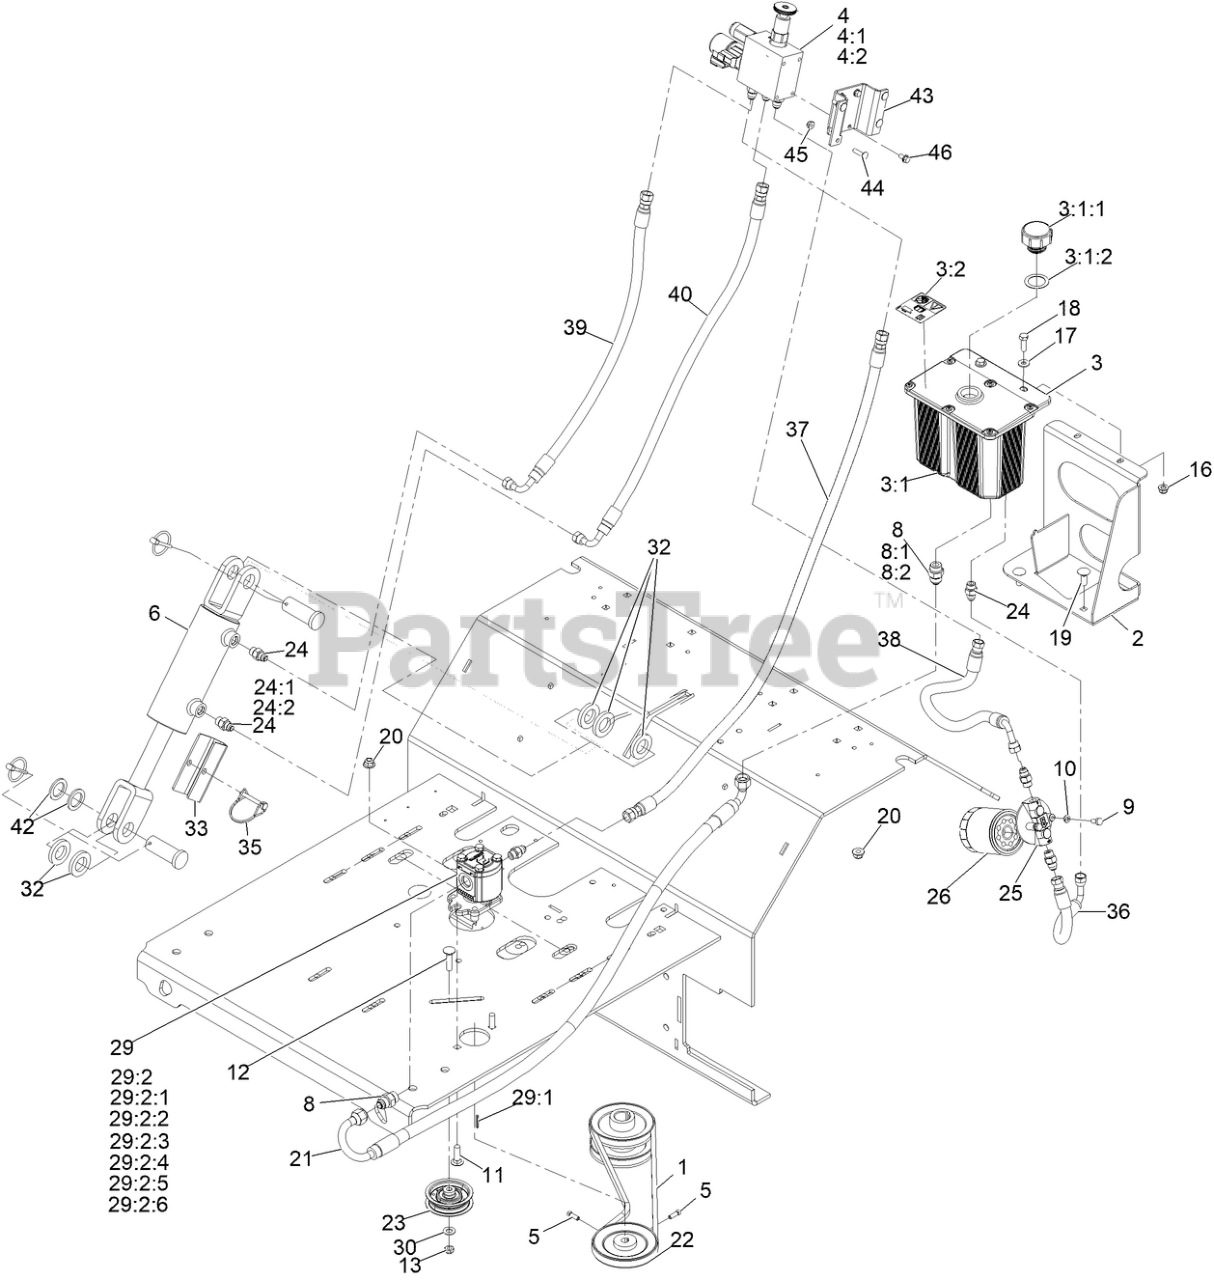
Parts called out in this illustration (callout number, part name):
1	BELT-4L SECTION
2	BRACKET-TANK, HYDRAULIC
3	RESERVOIR ASM
3:1	Tank-Hydraulic
3:1:1	Cap-Reservoir, HYD
3:1:2	GASKET-CAP
3:2	DECAL-WARNING
4	Manifold ASM
4:1	E Coil-12V Dc
4:2	FITTING-STRAIGHT
5	SCREW-SQH
6	HYD CYLINDER ASM
8	FITTING-STRAIGHT
9	SCREW-HH
10	WASHER-LOCK
11	BOLT-CARR
12	SCREW-CARR
16	NUT-HF, NI
17	WASHER-FLAT
18	SCREW-HH
19	BOLT-CARR
20	NUT-HF, NI
21	HOSE-HYDRAULIC
23	PULLEY-IDLER, FLAT
24	FITTING-STRAIGHT
24:1	BOSS O-RING
25	HEAD-FILTER
26	FILTER-25 MICRON, BI-DIRECTIONAL
29	HYDRAULIC PUMP ASM
29:1	KEY-SQUARE
29:2	SEAL KIT
29:2:1	Seal-Anti Extrusion
29:2:2	Seal-Anti Extrusion
29:2:3	Seal-Shaft
29:2:4	Seal-Upper
29:2:5	Seal
29:2:6	O-Ring
30	WASHER-FLAT
33	STOP-CYLINDER
35	PIN-HITCH
36	HOSE-HYDRAULIC, LP
37	HOSE-HYDRAULIC
38	HOSE-HYDRAULIC
39	HOSE-HYDRAULIC
40	Hydraulic Hose ASM
42	WASHER-THRUST
43	Bracket-Sensor, Control (Depth)
44	SCREW-CARR
46	SCREW-HWH
